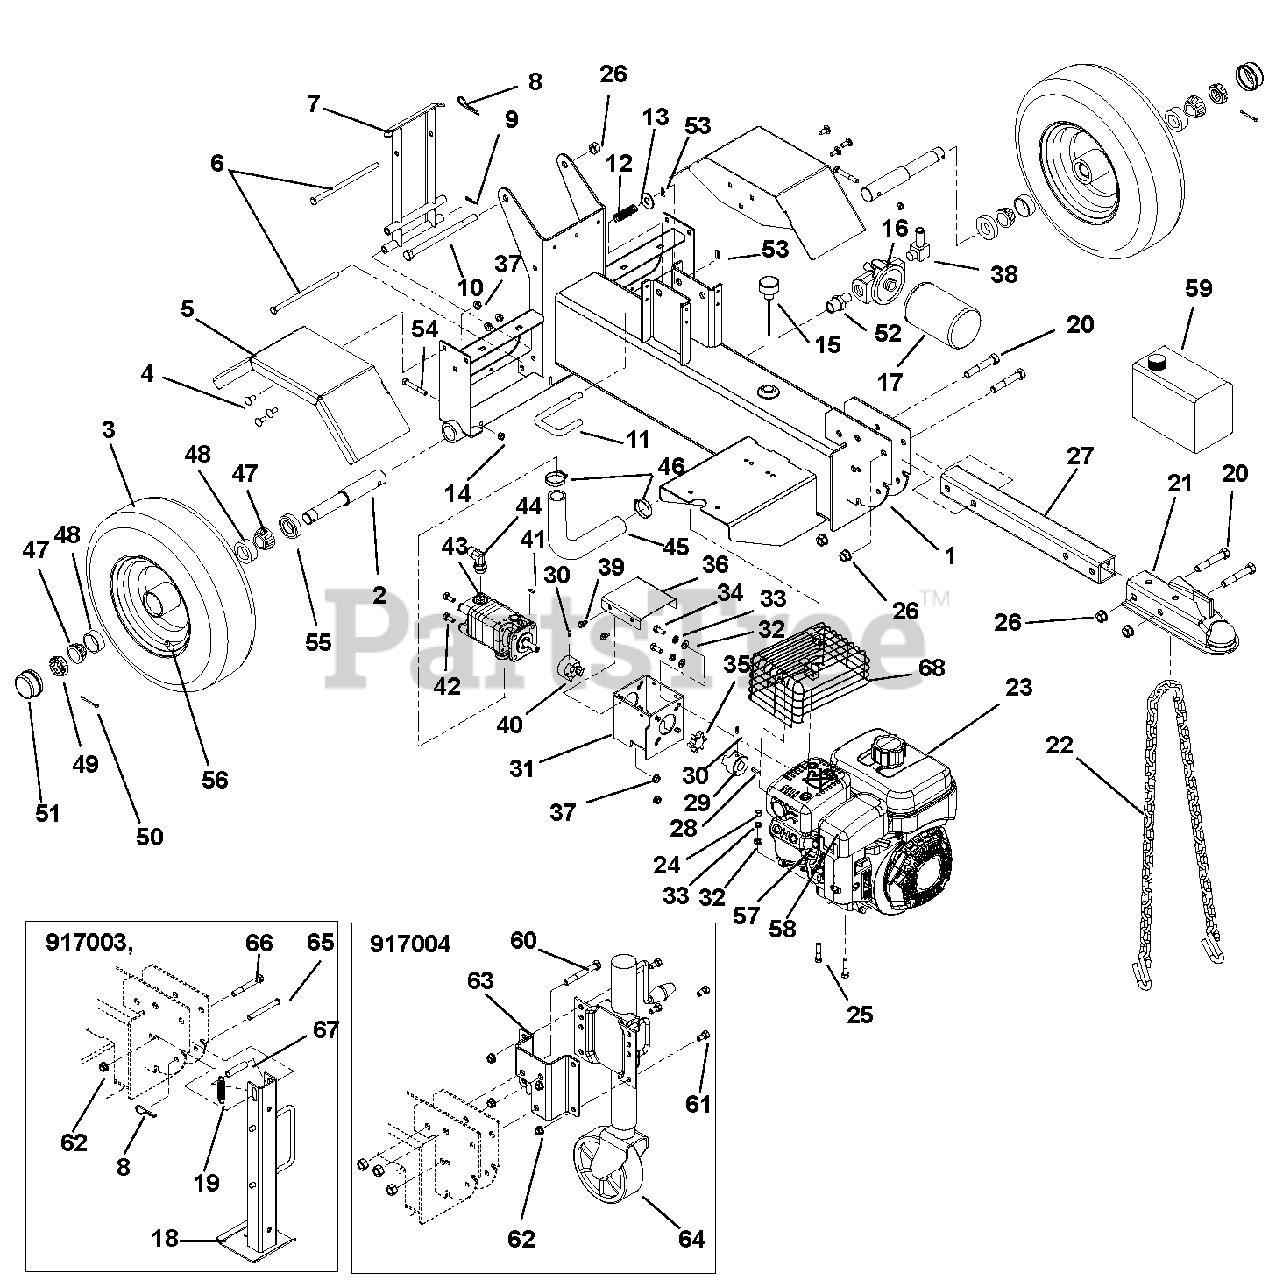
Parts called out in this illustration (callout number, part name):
1	Chassis, Splitter With Safety Decal
2	Axle, Splitter
3	Wheel, Splitter (Includes Items 47, 48, 55 and 56)
4	Bolt, Round Head Square Neck .31-18 x .75
6	Pin, Lock
7	Stand, Rear With Decals
8	Hairpin, #7 Clip .094 x .31
9	Pin, Hair #25
10	Bolt, Hex .50-13 x 7.50
11	Lock, Beam
12	Spring, Compression .058 x .65 x 2.13
13	Washer, Flat Steel .563 x 1.38 x .109
14	Nut, Locking Center .31-18
15	Breather, Dipstick
16	Head, Filter 3/4 NPT Bypass
17	Element, Filter
18	Stand, Jack (917003)
19	Spring, Tension .063 x .625 x 2.50 (917003)
20	Bolt, Hex .50-13 x 3.00 Grade 5
21	Hitch, Ball 2-Inch
22	Chain, Safety
23	Engine, Subaru SP170, CARB (917003, 301)
24	Nut, Hex .31-18
25	Bolt, Hex .31-18 x 1.50
26	Nut, Locking Center .50-13
27	Bar, Hitch With Decals
28	Key, Square .188 x .75 x .188
29	Hub, Drive Coupling 3/4 Inch
30	Screw, Set .25-20 x .38 Socket Head Cup Point Nyloc
31	Bracket, Pump Mount
32	Washer, Flat Steel .344 x .688 x .065
33	Washer, Locking .312 x .097 Heavy
34	Bolt, Hex .31-24 x .75
35	Spider, Urethane
36	Cover, With Decals
37	Nut, Locking Top Flange .31-18
38	Fitting, Hydraulic 4501-10-12-FG
39	Screw, Tapping .25-20 x .50 Hex Washer Head Thread Rolling
40	Hub, Drive Coupling 1/2 Inch
41	Key, Woodruff .125 x .50 x .20
42	Bolt, Hex .31-18 x .75
43	Pump, Splitter 11 GPM (917003, 301)
44	Fitting, Hydraulic 6801-8-8
45	Hose, Hydraulic Suction 16G4H x 13.5
46	Clamp, Hose 1.50 x .81 x 1.42
47	Bearing, Cone With Grease
48	Bearing, Cup 1.980 x .420
49	Nut, Slotted 1.0-14
50	Pin, Center .15 x 1.50
51	Cap, Dust
52	Fitting, Hydraulic 5404-12-12
53	Clip, Spring
54	Bolt, Hex .31-18 x 2.25
56	Valve Stem Assembly
57	Spark Plug
58	Filter, Air
59	Oil, Hydraulic 2.5 Gallon ISO Grade 32
60	Bolt, Hex .50-13 x 3.25 (917004)
61	Bolt, Hex .38-16 x .75 (917004)
62	Nut, Locking Top Flange .38-16
63	Bracket, Mounting (917004)
64	Stand, Jack With Wheel (917004)
65	Pin, Clevis .368/.373 x 3.25 (917003, 301)
66	Bolt, Hex .38-16 x 3.00 (917003, 301)
67	Spacer, Wheel (917003, 301)
68	Guard, Muffler (917301)
